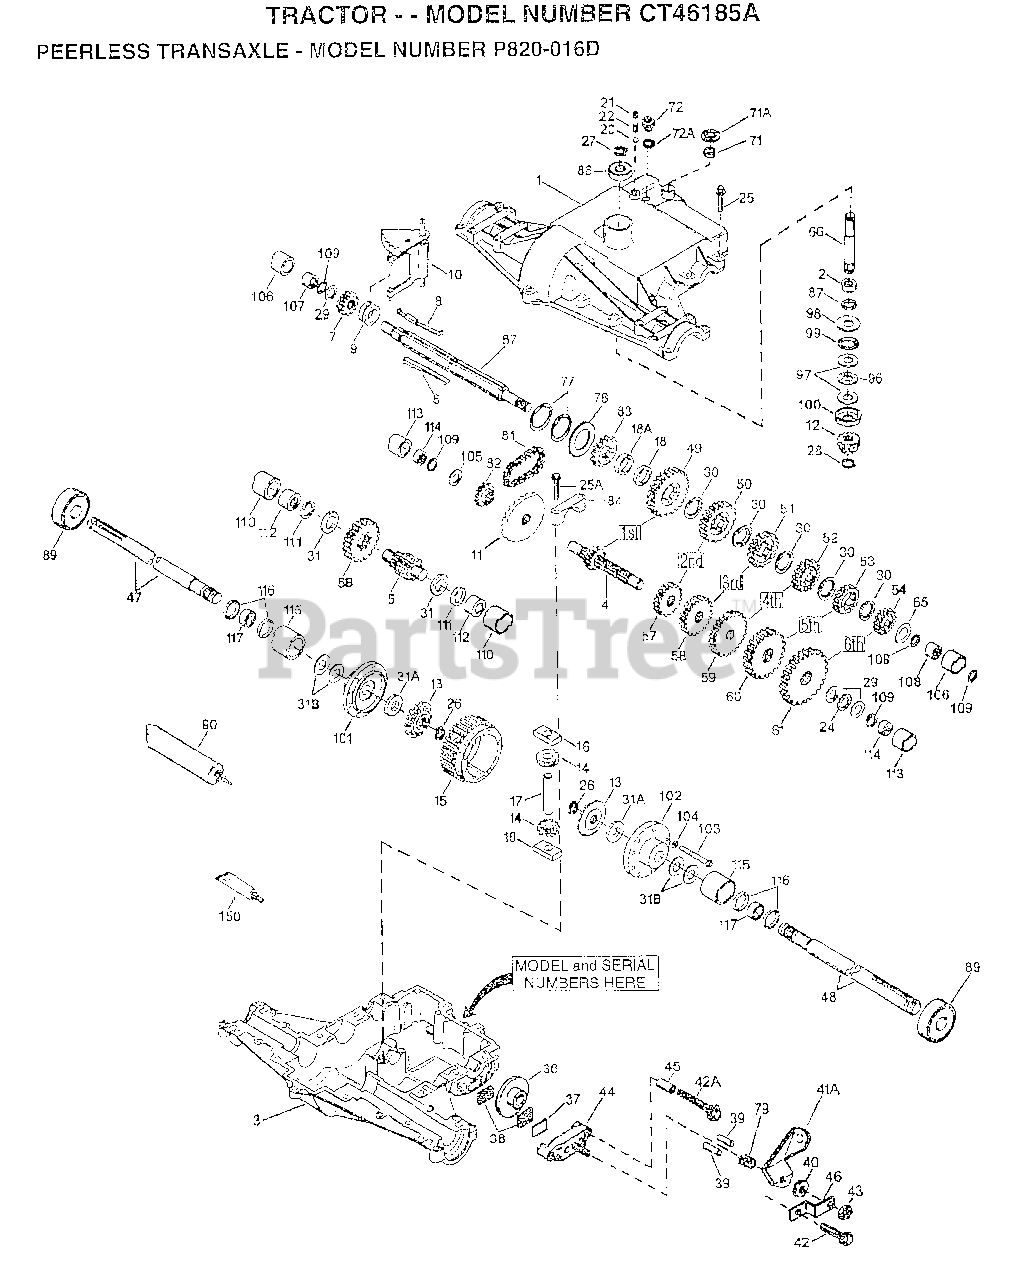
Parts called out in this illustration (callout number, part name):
1	COVER TRANSAXLE
2	BEARING NEEDLE
3	CASE TRANSAXLE
4	SHAFT COUNTER
5	SHAFT, OUTPUT, 9T
6B	GEAR, OUTPUT, 35T
7	GEAR, SPUR, 15T
9	COLLAR, SHIFTER
11	GEAR BEVEL, 33T
12	BEVEL PINION, 13T
14	PINION, 10T
15	GEAR, RING, 31T
16	BLOCK DRIVE
18	SPACER, .350/.340 THICK
18A	SPACER, .276/.268 THICK
20	BALL STEEL, 5/16" DIA.
21	SCREW, 3/8-16 X 3/8"
24	THRUST BEARING
25	SCREW, 5/16-18 X 1-1/4
28	RETAINING RING
29	WASHER THRUST
30	WASHER THRUST
31	WASHER THRUST
31B	WASHER THRUST
37	PLATE BRAKE PAD
41A	LEVER BRAKE
42A	SCREW, 1/4-20 X 2-1/4
43	LOCKNUT 5/16-24
44	HOLDER BRAKE PAD
46	BRKT BRAKE LEVER
47	AXLE, 12-5/16" LONG
48	AXLE, 16-3/16" LONG
49	GEAR, SPUR, 41T
50	GEAR, SPUR, 35T
51	GEAR, SPUR, 30T
52	GEAR, SPUR, 25T
53	GEAR, SPUR, 22T
54	GEAR, SPUR, 19T
57	GEAR, SPUR, 15T
58	GEAR, SPUR, 20T
59	GEAR, SPUR, 25T
60	GEAR, SPUR, 28T
61	GEAR, SPUR, 31T
65	WASHER, THRUST
66	SHAFT INPUT
67	SHIFTER & BRAKE SHAFT
71	SEAL SQUARE CUT
72	THREADED PLUG 9/16-18
76	WASHER, THRUST
77	INVERTED RETAINING RING
81	CHAIN, ROLLER
82	SPROCKET 9T
83	SPROCKET 18T (REV)
84	BEARING CAP
87	OIL SEAL 3/4
88	BEARING BALL
89	BEARING BALL
90	GREASE BENTONITE, 32 OZ.
96	BEARING THRUST
97	WASHER THRUST
100	WASHER CUPPED
101	CARRIER DIFF THREADED HOLES
102	CARRIER DIFF
103	SCREW, 1/4-20 X 2-1/4
104	WASHER LOCK 1/4
107	BEARING NEEDLE
108	BEARING NEEDLE
110	SLEEVE STEPPED
111	RING SQ CUT
112	BEARING NEEDLE CAPPED
113	SLEEVE STEPPED
114	BEARING NEEDLE CAPPED
115	SLEEVE STEPPED
116	RING SQ CUT
117	BEARING NEEDLE
150	LIQUID GASKET RTV SILICONE
